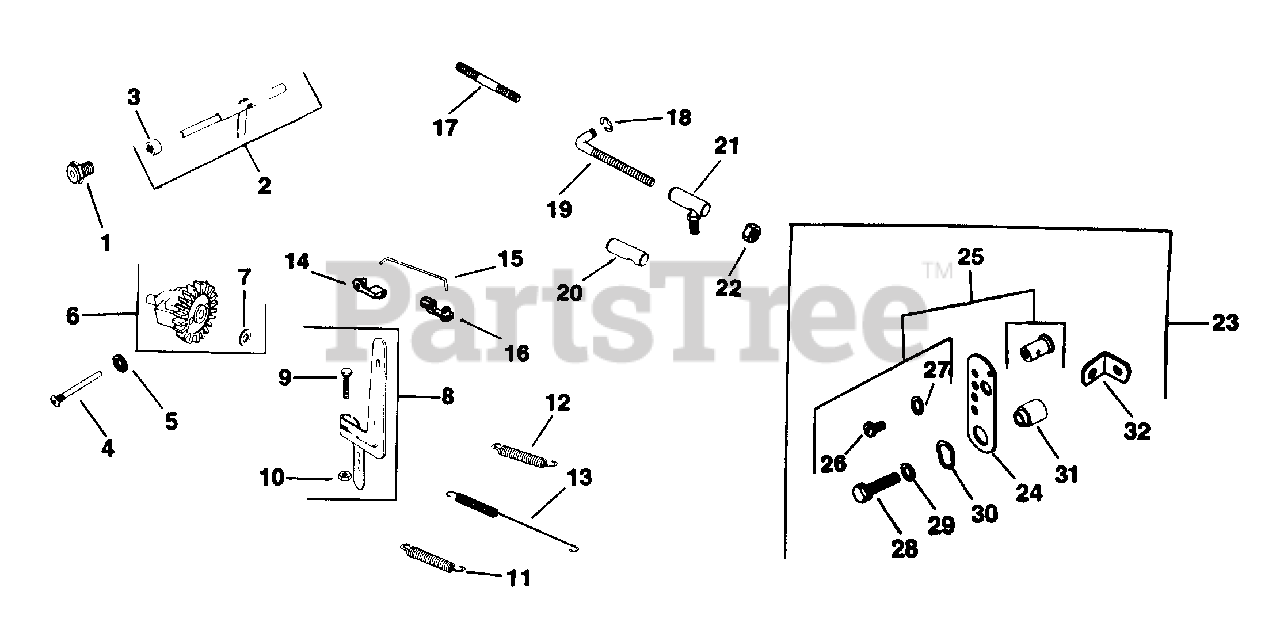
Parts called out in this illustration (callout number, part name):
1	BUSHING
2	KIT, SHAFT
3	SPACER USE 25 112 17-S
6	KIT, GOVERNOR GEAR
7	WASHER
8	LEVER
10	PALNUT, 1/4-20
18	RETAINER
20	BODY - DISCONTINUED
22	NUT, MACH SCREW #10-32 GRD 2 USE 25 100 18-S
23	BRACKET - DISCONTINUED
24	BRACKET
25	KIT, CLAMP
26	SCREW - USE 41 086 20
27	WASHER, FLAT 1/4"
29	WASHER, FLAT 1/4" (O.D. 1/2")
30	WASHER, SPRING 11/32"
32	BRACKET, ADJUSTING SCREW - DISCONTINUED
